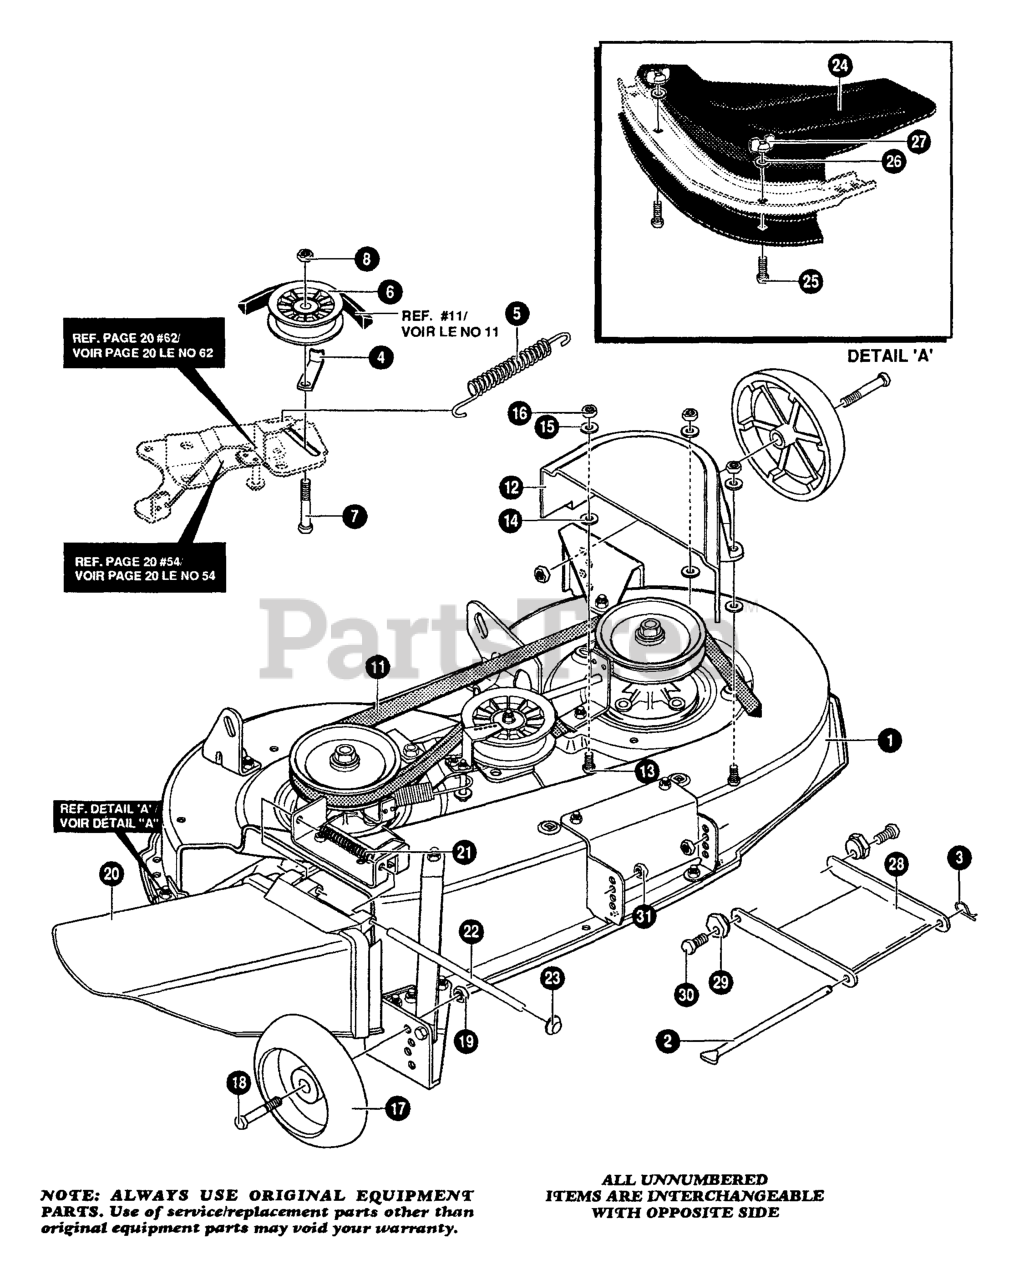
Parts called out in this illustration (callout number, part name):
2	ROD, HITCH
3	PIN, HAIR
4	RETAINER, BELT
5	SPRING, TENSION
6	PULLEY, IDLER
7	BOLT
11	BELT, V
12	GUARD, BELT LH
14	PUSHNUT
15	WASHER
17	GAUGE WHEEL
19	NUT
20	CHUTE DEFLECTOR
21	SPRING, DEFLECTOR
22	ROD, PIVOT
23	NUT, PUSH ON
24	MULCHER PLUG
27	NUT, WING
28	BRKT, LINK FRONT
